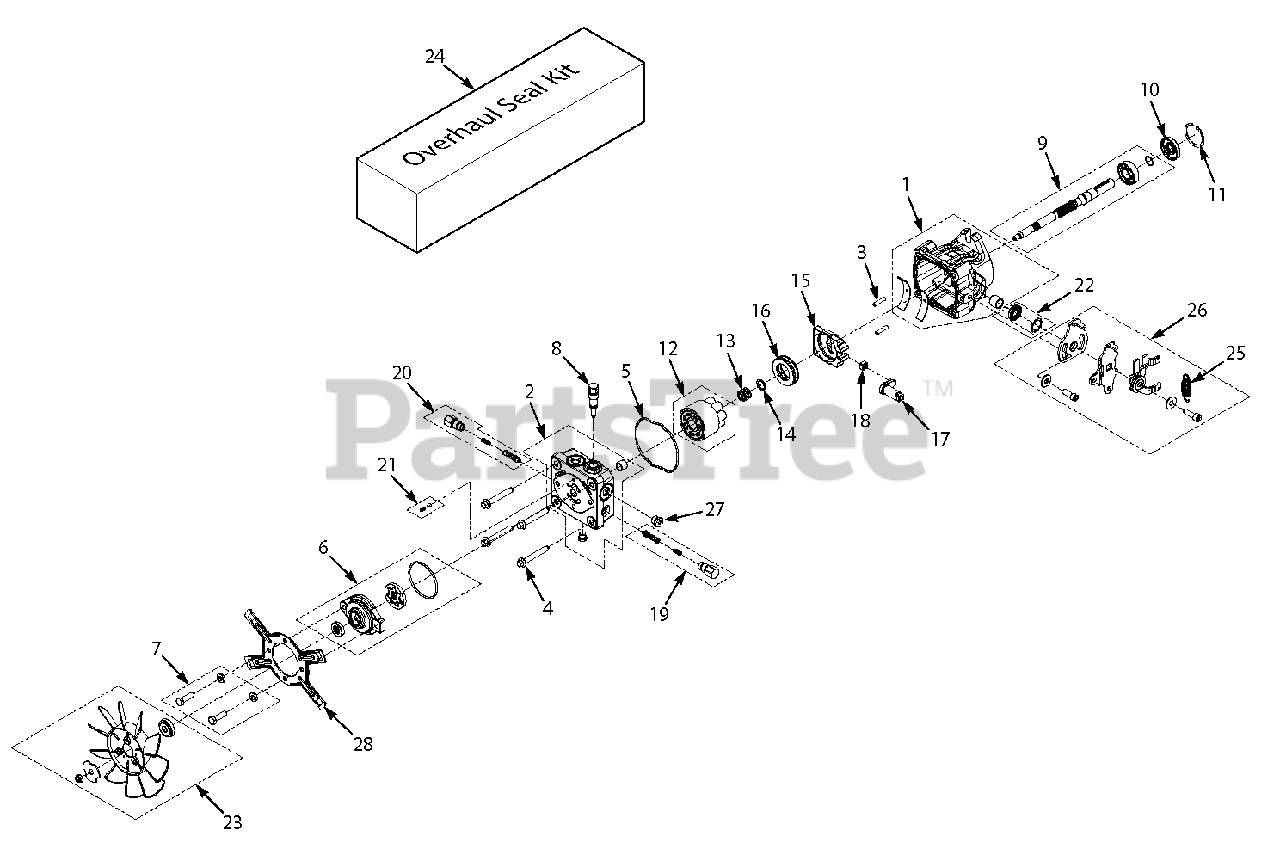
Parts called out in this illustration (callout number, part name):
1	Kit, Housing
2	Kit, End Cap
3	Pin, .219 x 1.000
4	Bolt, M8 X 1.25 mm
5	Gasket, Housing
6	Kit, Charge Pump
7	Kit, Charge Pump Bolts
8	By-Pass Valve
9	Kit, Shaft
10	Seal, 17 x 40 x 7 Lip
11	Ring, Retaining .156 Internal
12	Kit, Block 12cc
13	Spring, Block
14	Washer, .59 x .79 x .04
15	Swashplate
16	Bearing, Thrust
17	Trunnion Arm
18	Slot Guide
19	Kit, Shock Valve - 160 Bar (.031 Orifice)
20	Kit, Shock Valve - 160 Bar (.031 Orifice)
21	Kit, Charge Relief
22	Kit, Seal - Trunnion Arm
23	Fan Assembly
24	Seal Kit
25	Spring
26	Kit, RTN
27	Plug, 9/16-18
28	Bracket, 7"
